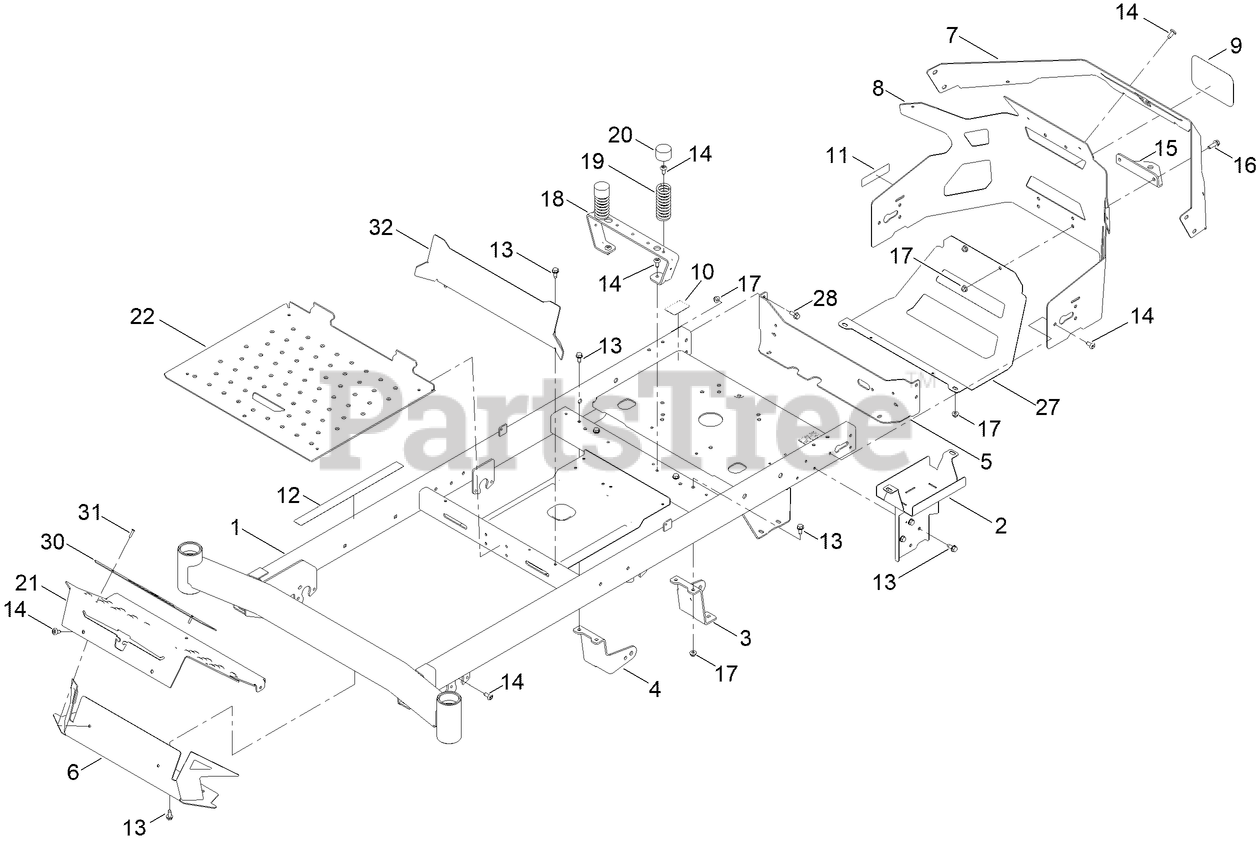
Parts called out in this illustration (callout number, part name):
1	SERVICE ASM-FRAME, TC
2	WA-BATTERY MOUNT
3	MOUNT-DRIVE, LH
4	MOUNT-DRIVE, RH
5	PLATE-MOUNT
6	FOOTREST-TOP
7	PLATE-REAR CLADDING TC
8	GUARD-ENGINE TC
10	DECAL-BYPASS
11	DECAL-SPARK ARRESTER
12	DECAL-WARNING
13	SCREW-HWHTF
15	BRACKET-HITCH
16	SCREW-HHF
17	NUT-HF
18	SUPPORT-SEAT
19	SPRING-COMPRESSION
20	CAP-PROTECTOR
21	PLATE-KICK
22	PAN-FLOOR
27	GUARD-MUFFLER [BLACK]
28	SCREW-HHF
30	PLATE- TOEBOARD
31	RIVET-TRIFOLD
32	PLATE-KICK
